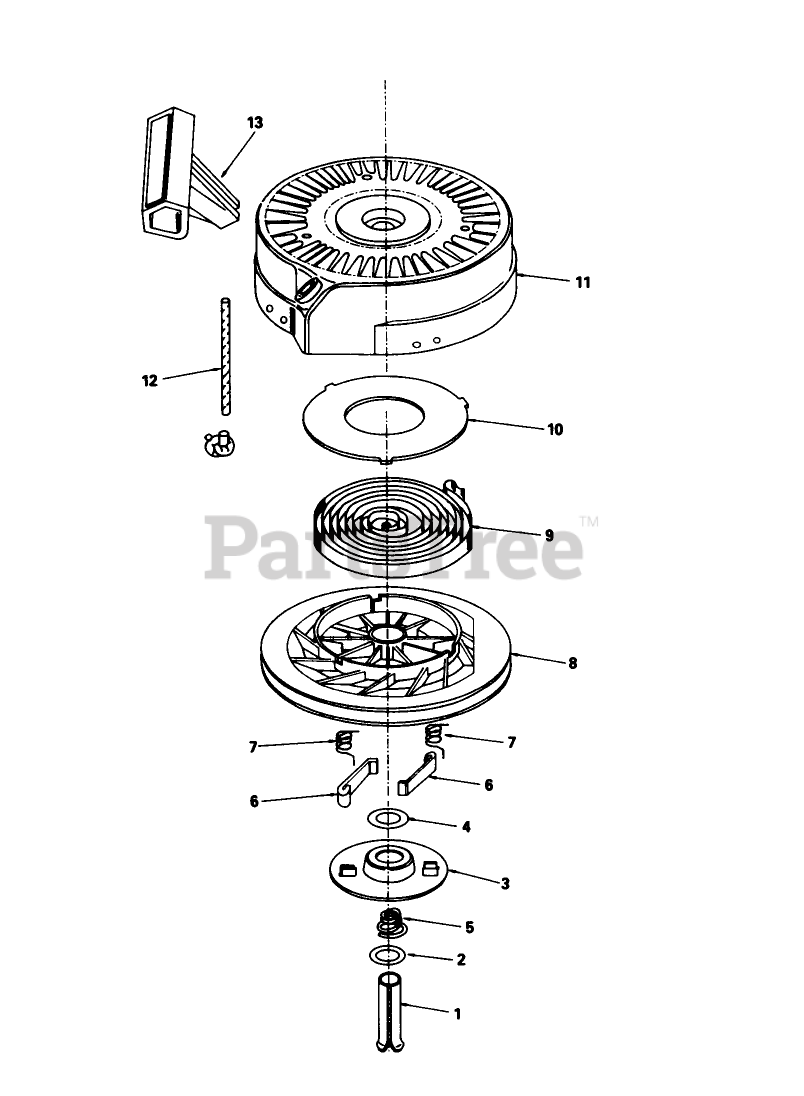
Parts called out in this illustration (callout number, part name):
1	Pin, Spring (Incl. Ref. #7)
2	Washer
3	Retainer
4	Washer
5	Brake Spring
6	Dog-Starter
7	Spring-Dog
8	Pulley
9	Rewind Spring
10	Cover-Spring
11	Housing-Starter
12	Rope-Starter (98 cut to length)
13	Handle-Starter
